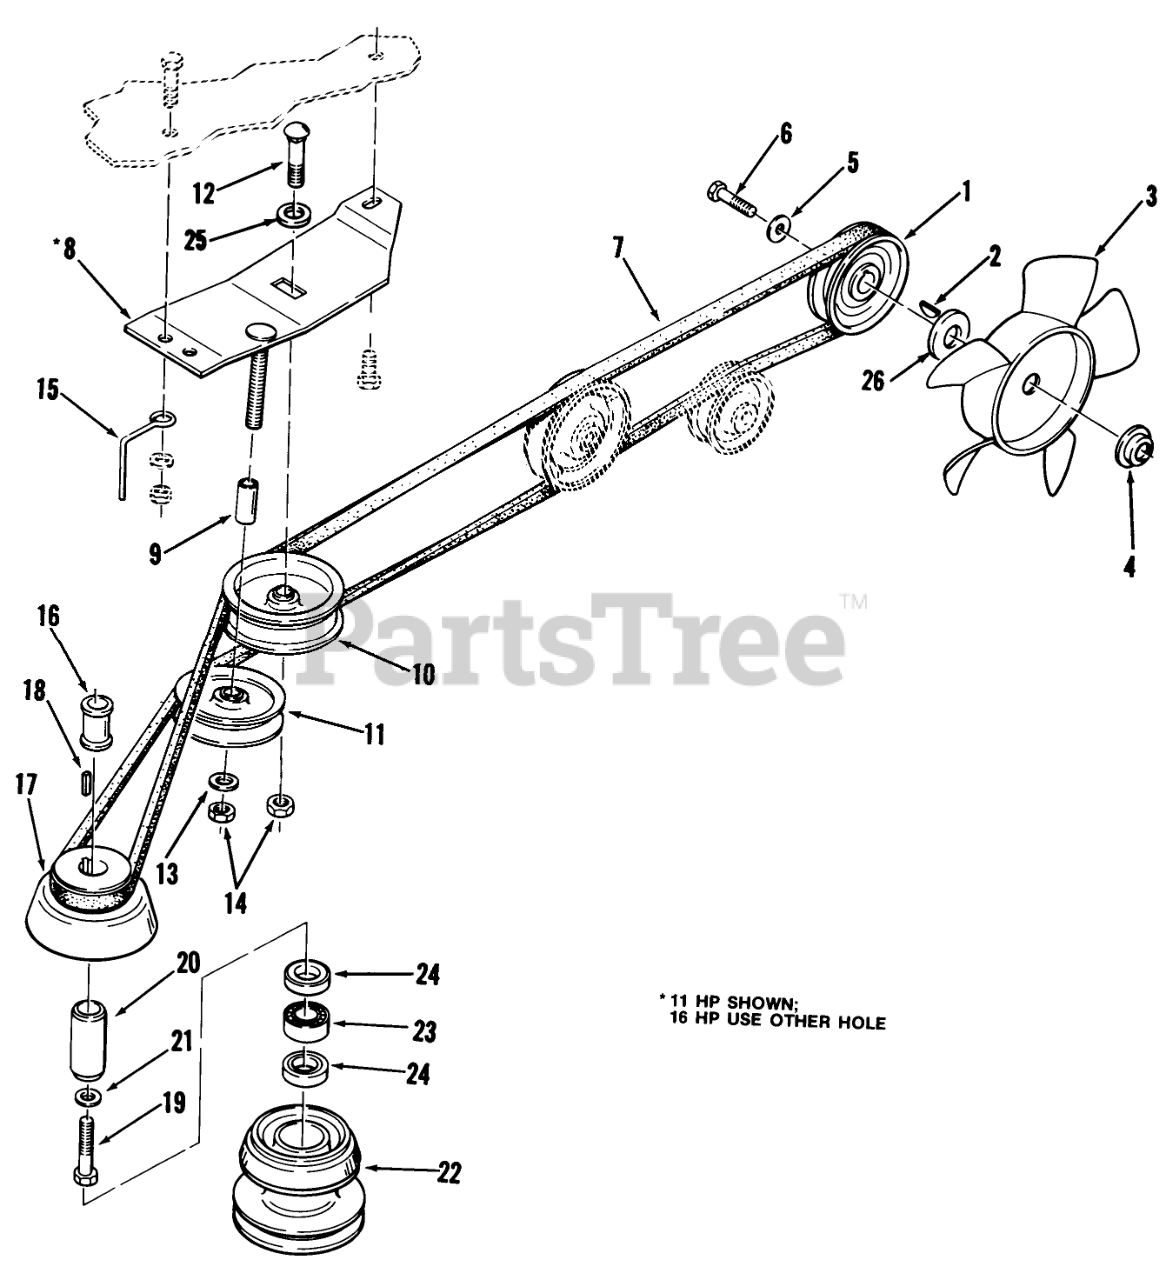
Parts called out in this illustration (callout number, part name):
1	PULLEY
2	KEY WOODR 1/8X1/2 DI
3	BLADE - FAN
4	SPACER FAN
5	WASHER
6	Bolt
7	V-BELT
7	BELT V
8	ASSY PULLEY BRACK R
9	Spacer
10	Flat Idler
11	PULLEY-IDLER STATION
12	Bolt
13	Washer
14	Nut
15	Belt Retainer
16	TUBE SPACER
17	PULLEY-ENGINE
19	HEX HD CAP SCREW
20	RACE BEARING
21	WASHER
22	Assy Pulley Mwr Dr
23	BRG-NEEDLE OPEN END
24	SEAL-OIL
25	Washer
26	Special Washer
